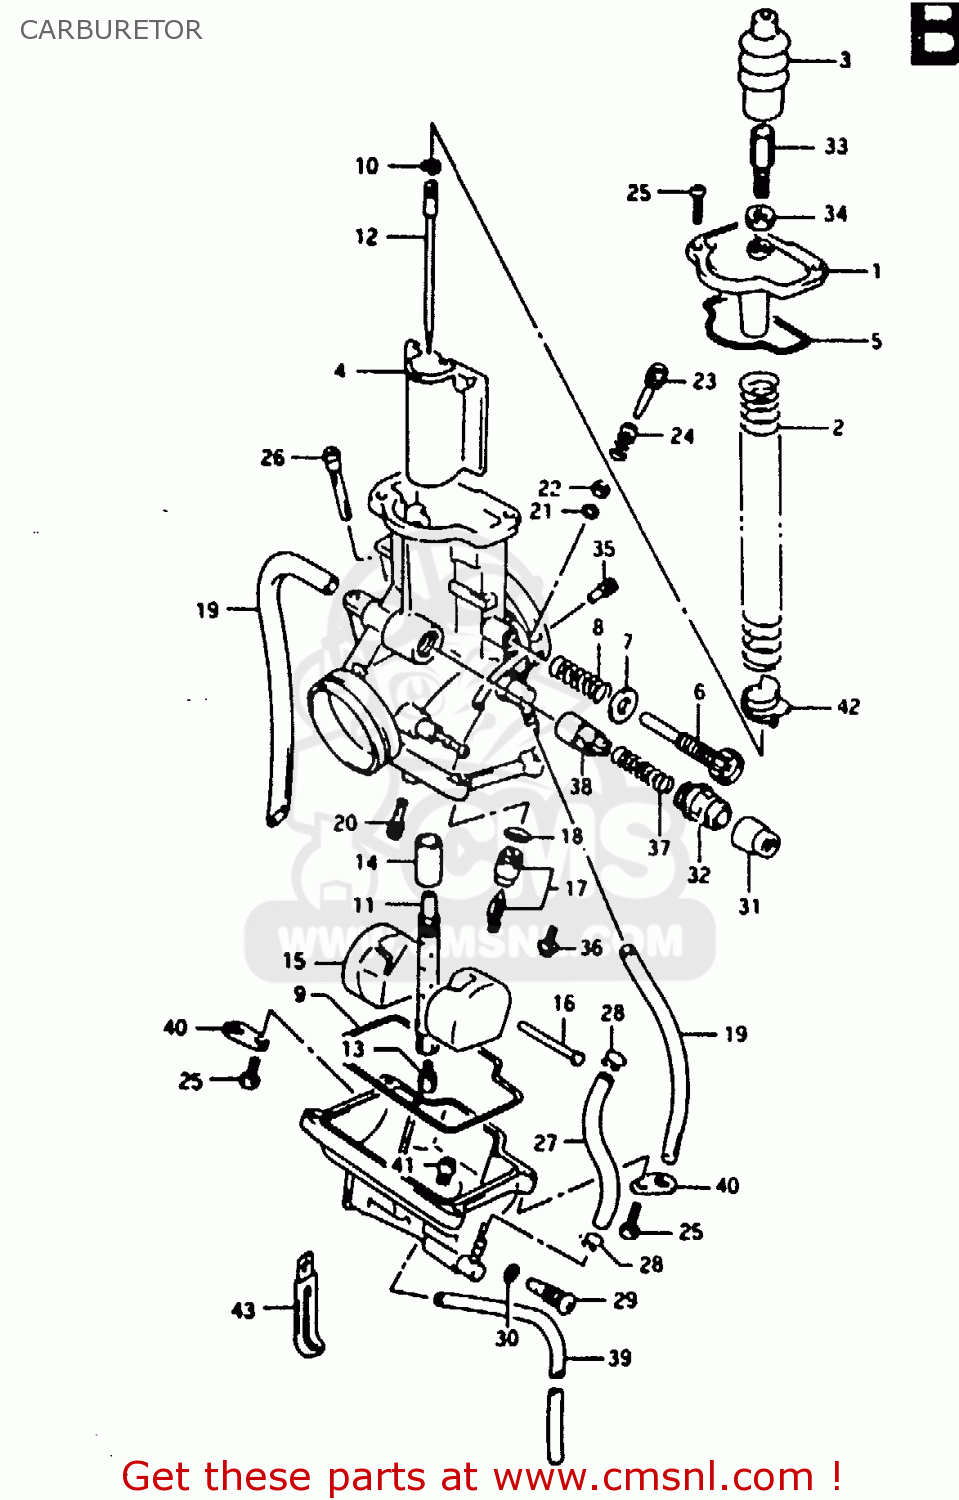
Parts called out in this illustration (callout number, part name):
1	CAP, TOP
2	SPRING
3	CAP,CABLE ADJUSTER
4	VALVE,PISTON(CA:1.5)
5	O RING,TOP CAP
6	ADJUSTER
7	WASHER
8	SPRING
9	GASKET,FLOAT CAHMBER (NAS)
10	CLIP,NEEDLE
11	JET,NEEDLE(P-3)
12	NEEDLE,JET
13	JET,MAIN(195)
14	RING
15	FLOAT
16	PIN,FLOAT
17	VALVE ASSY,NEEDLE
18	O-RING,NEEDLE VALVE
19	HOSE
20	JET,PILOT(25)
21	O RING,PILOT AIR SCREW
22	WASHER
23	SCREW,PILOT AIR
24	SPRING,THROTTLE SCREW
25	SCREW
26	FILTER
27	HOSE SET
28	CLIP
29	PLUG,DRAIN
30	O RING
31	CAP
32	HOLDER,GUIDE
33	ADJUSTER,CABLE
34	NUT
35	JET,AIR(0.6)
36	SCREW
37	SPRING
38	PLUNGER,STARTER
39	HOSE
40	PLATE,CARBURETOR
41	JET, MAIN
42	RING
43	CLAMP
